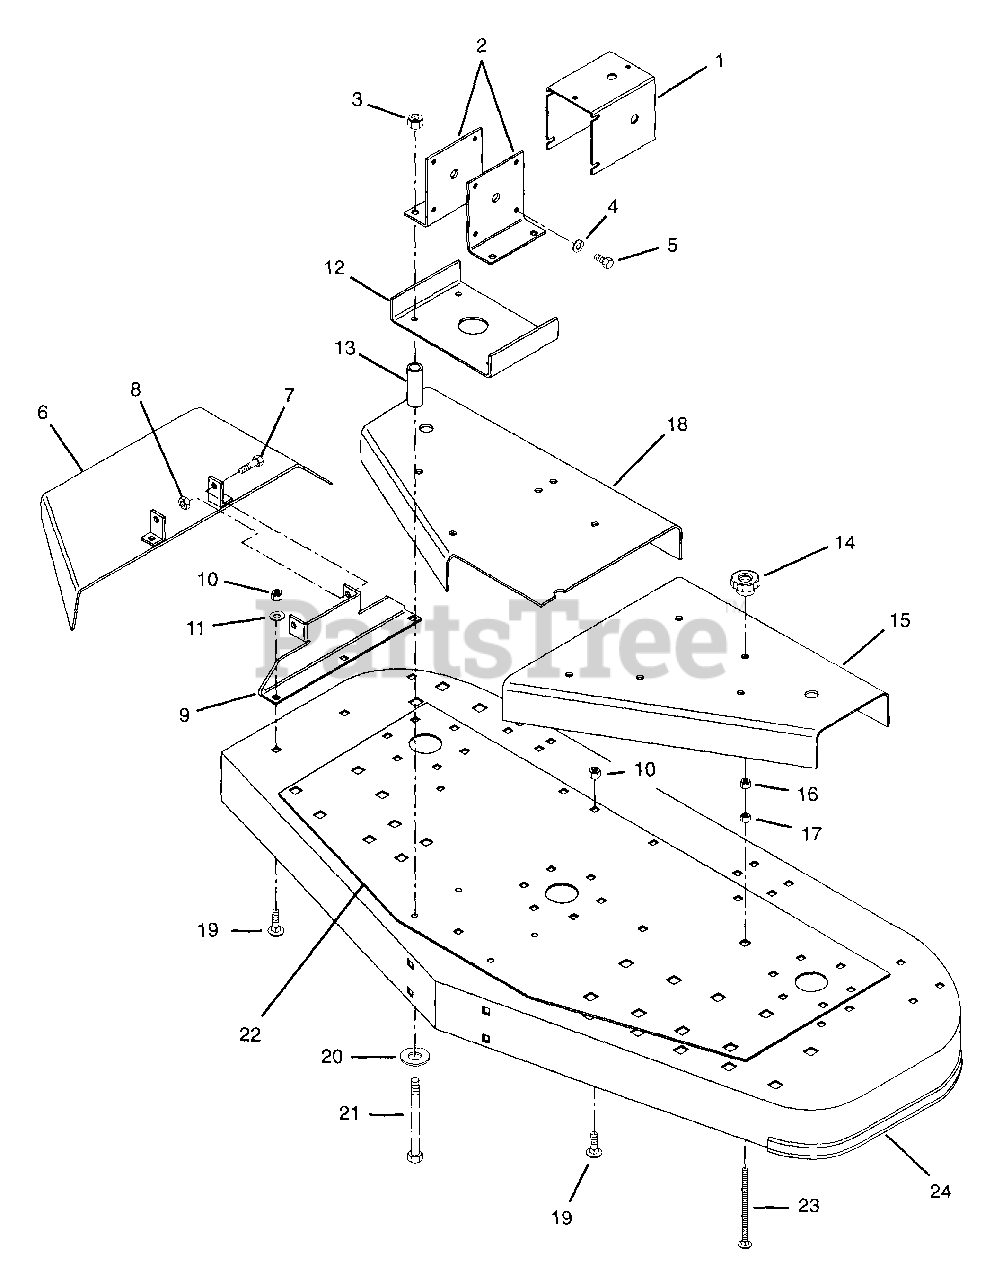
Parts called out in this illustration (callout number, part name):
1	Shield, U-Joint
2	Bracket, Gearbox Mounting
3	Nut-Locking-Nylon .50-13 Grade 5
4	Washer-Lock .375 x .094
5	Bolt-Hex .380-16 x .875
6	Weldment, Discharge Chute
7	Bolt-Hex .25-20 x .875
8	Nut-Locking-Nylon .250-20 Grade 2
9	Bracket, Discharge
10	Nut-Locking-Nylon .375-16 Grade 2
11	Washer-Flat-Steel .406 x .812 x .065
12	Plate, Support
13	Spacer .562 x 1.00 x 2.00
14	Knob
15	Cover, Belt Silkscreen
16	Nut-Locking-Nylon .312-18 Grade 2
17	Nut-Jam .312-18
18	Cover, Belt Right Hand
19	Bolt-Round Head Square Neck .38-16 x 1.0
20	Washer-Flat-Steel .531 x 1.062 x .095
21	Bolt-Hex .50-13 x 3.75
22	Plate, Deck Support
23	Bolt-Round Head Square Neck .31-18 x 4.0
24	Weldment, 60" Mower Deck
